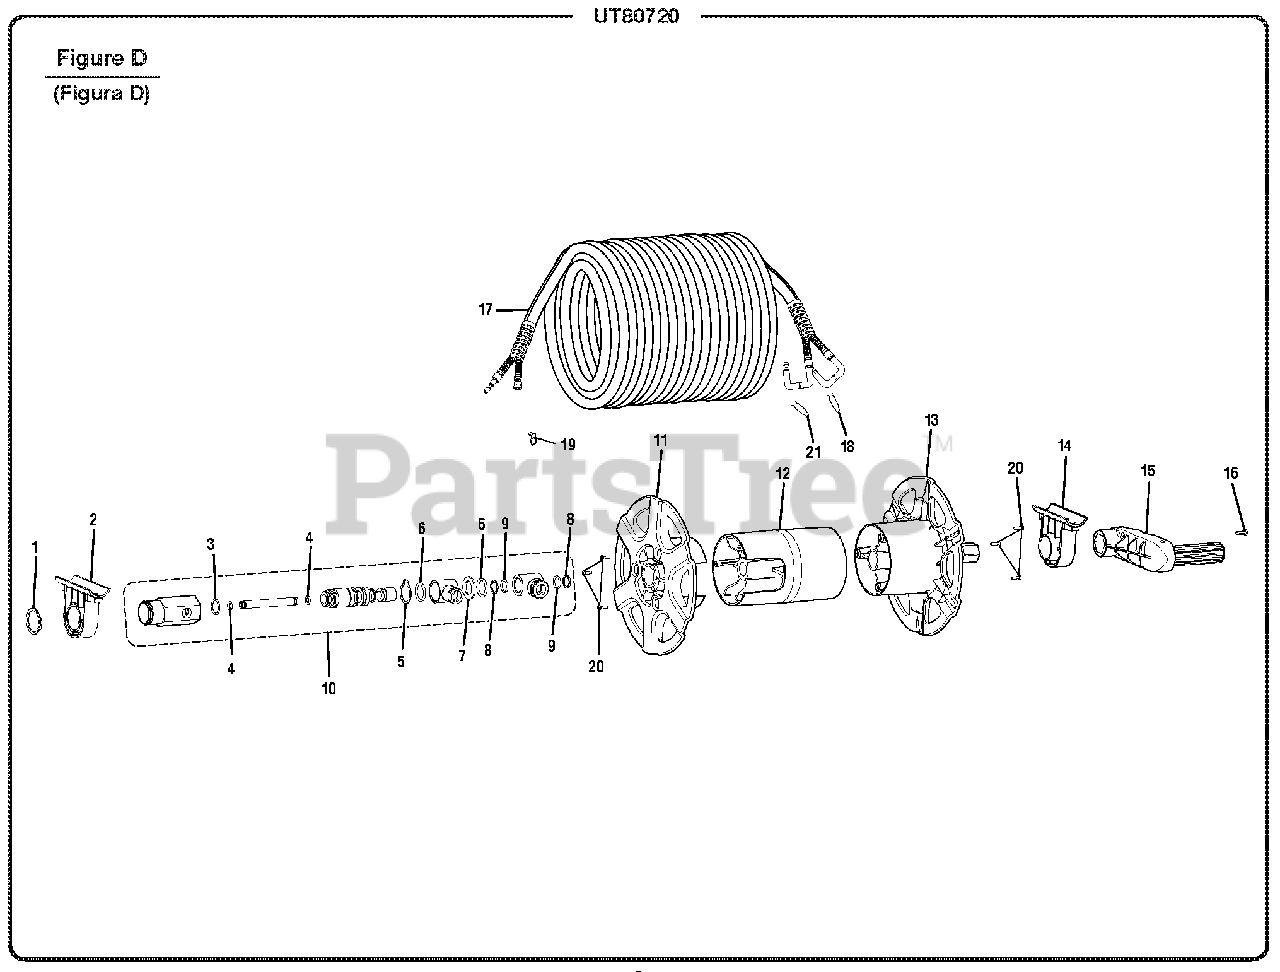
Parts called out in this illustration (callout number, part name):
1	Retaining Ring
2	Mounting Bracket (Left)
5	Retaining Ring
7	Washer (ID16.2 x OD28 x 2.5t)
8	Backup Ring (ID13 x OD16 x 1.4t)
10	Water Inlet
11	Cover (Left)
12	Middle Body
13	Cover (Right)
14	Mounting Bracket (Right)
15	Handle Assembly
16	Screw (M4 x 12 mm, Pan Hd.)
18	Low Pressure Hose Clip
19	Low Pressure Trigger Handle Clip
20	Screw (M3 x 10 mm)
21	High Pressure Hose Clip
